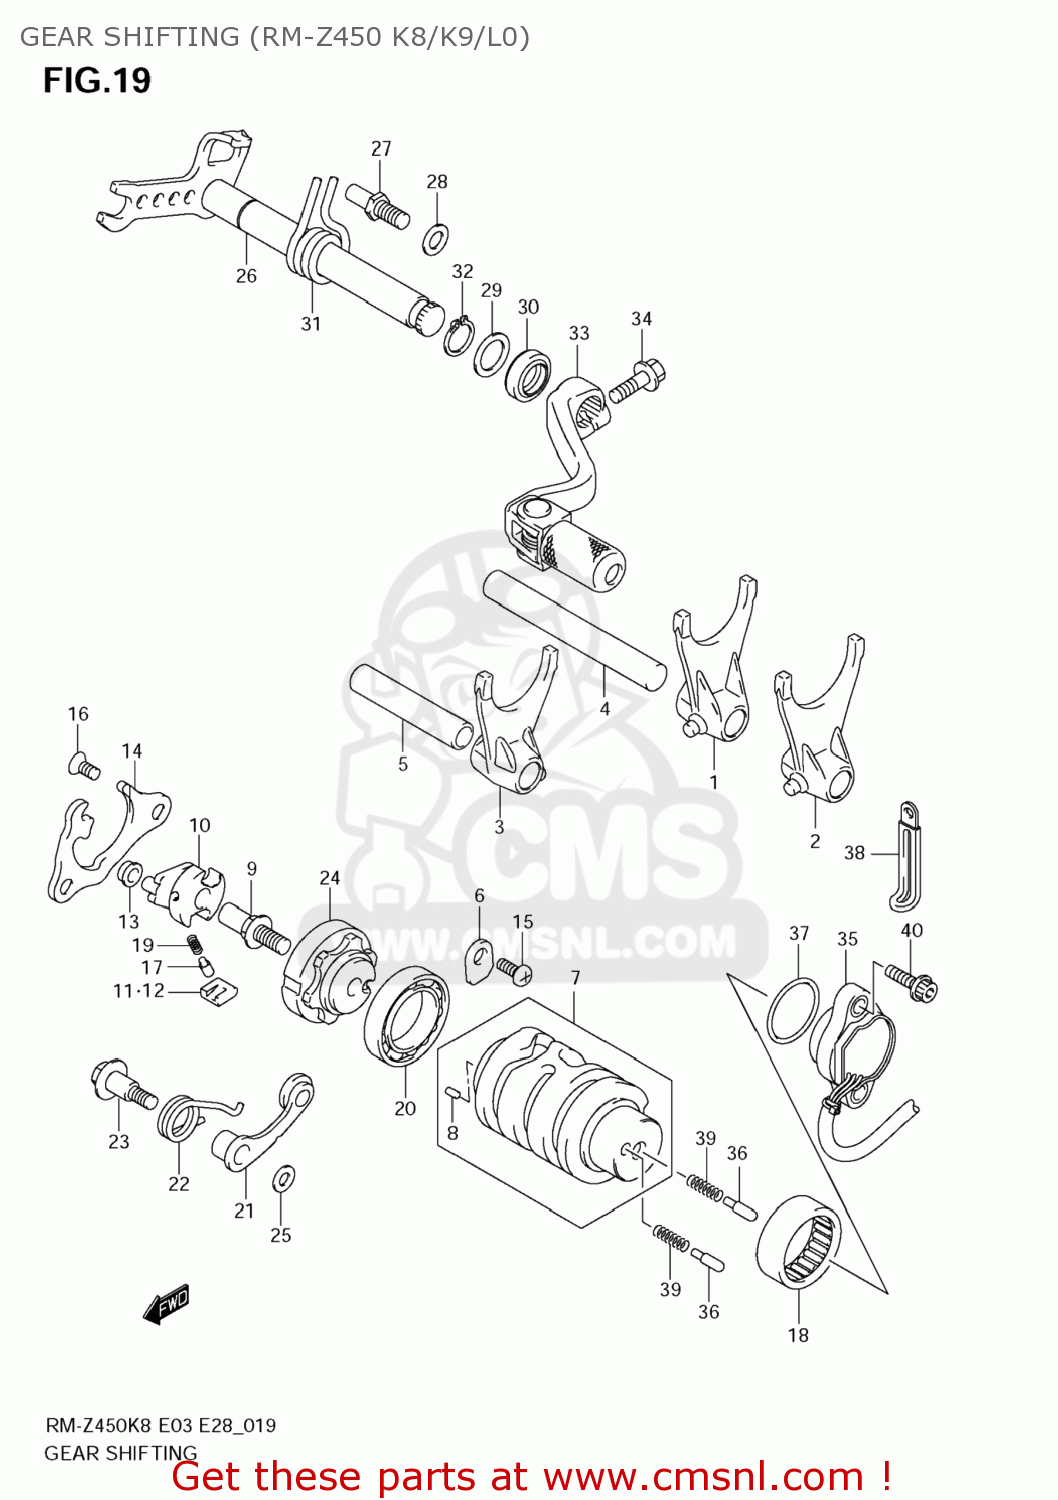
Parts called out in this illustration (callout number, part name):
1	FORK,GEAR SHIFT NO.1
2	FORK,GEAR SHIFT NO.2
3	FORK,GEAR SHIFT NO.3
4	SHAFT,GEAR SHIFT FORK NO.1
5	SHAFT,GEAR SHIFT FORK NO.2
6	RETAINER
7	CAM,GEAR SHIFT
8	PIN
9	PIN,GEAR SHIFT CAM
10	SHIFTER,GEAR SHIFT CAM
11	PAWL,GEAR SHIFT NO.1
12	PAWL,GEAR SHIFT NO.2
13	ROLLER,GEAR SHIFT CAM SHIFTER
14	LIFTER,GEAR SHIFT PAWL
15	BOLT(6X12)
16	SCREW(6X12)
17	PIN
18	BEARING(25X32X12)
19	SPRING
20	BEARING
21	STOPPER,GEAR SHIFT CAM
22	SPRING,GEAR SHIFT CAM STOPPER
23	BOLT,SHIFT CAM STOPPER
24	PLATE,GEAR SHIFT CAM STOPPER
25	WASHER
26	SHAFT,GEAR SHIFT
27	STOPPER,GEAR SHIFT ARM
28	SHIM(8.8X14X1)
29	SHIM(14X20X1)
30	SEAL,OIL(14X22X6)
31	SPRING
32	CIRCLIP
33	LEVER ASSY,GEA
34	BOLT
35	BASE ASSY,GEAR SHIFT TERMINAL
36	PIN(5X15.5)
37	O RING(D:2.4,ID:26.2)
38	CLAMP(L:45)
39	SPRING
40	BOLT
